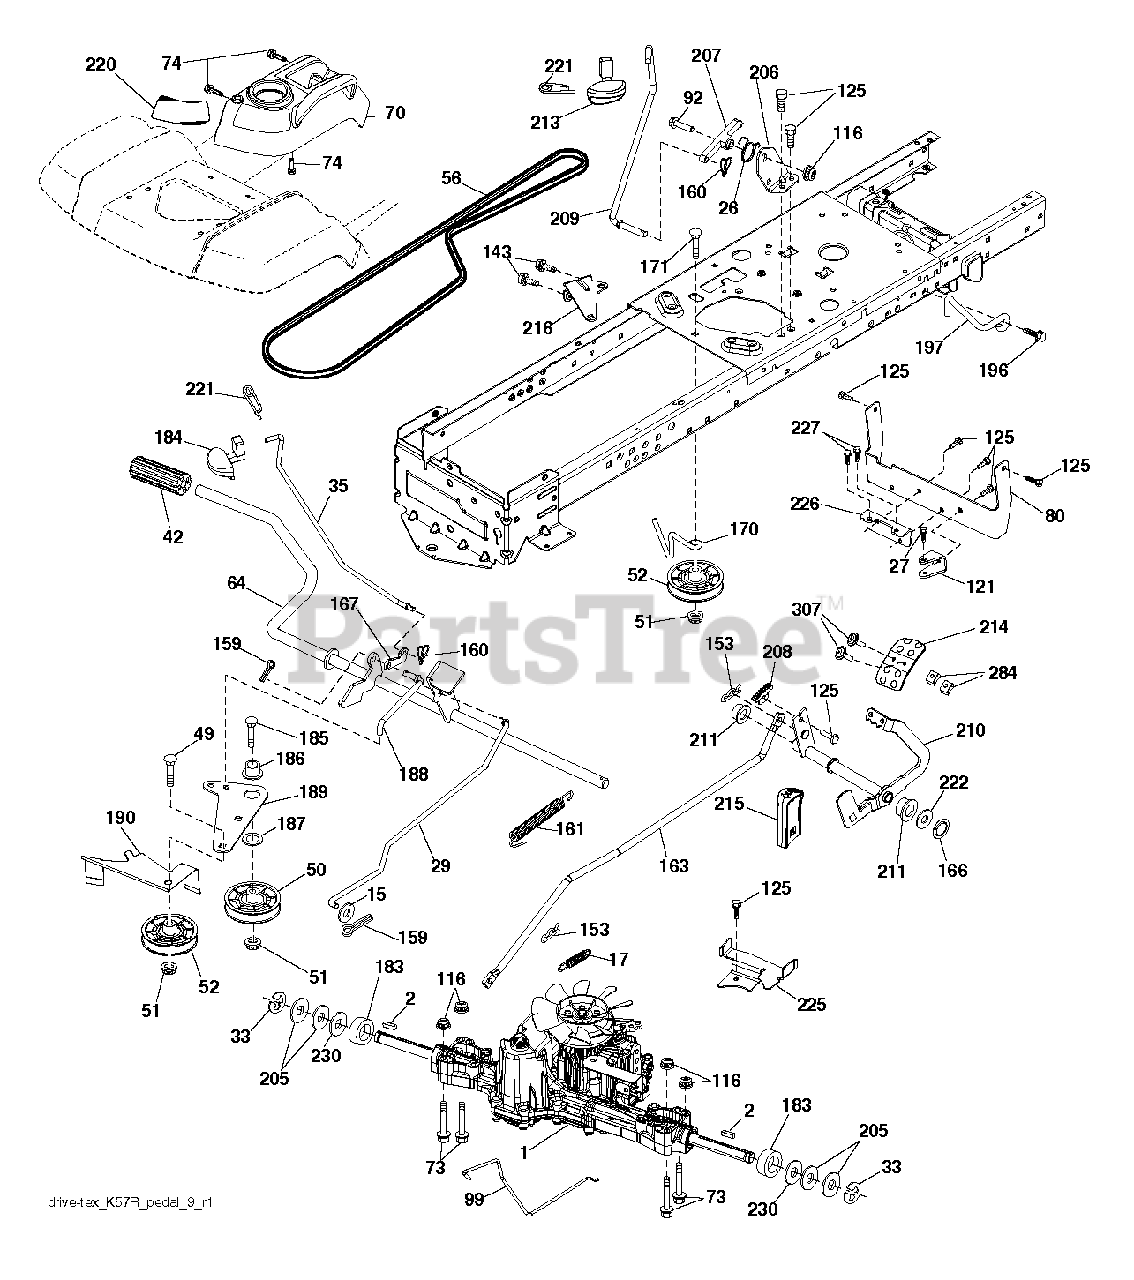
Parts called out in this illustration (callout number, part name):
2	SQUARE KEY
15	WASHER
17	SPRING.BRAKE.K46.GREEN
26	SPRING.RETURN.CRUISE
29	ROD.BRAKE.K46
33	E RING HYT
35	ROD .BRAKE. PARKING. GT. HUSQ.
42	PEDAL COVER T
50	IDLER.FLAT.910.OFFSET
51	NUT LOCK FLG 3/8-16 UNC
52	IDLER.V-GROOVE.910.OFFSET
56	V-BELT.MOWER.92.40.42/K46
64	SHAFT.ASM.PEDAL.BRK.CNTR
70	CONSOLE.ASM.RH.GT.FC.HUSQ
74	SCREW.HI-LO.CONSOLE
80	STRAP.TORQUE.K46.K57R.TT
92	BOLT
99	ROD.SPRING.BYPASS.K46.LT.Z
116	NUT LOCK HEX FLANGE 5/16-18
121	BRACKET.TORQUE.K57R.3POINT
125	SCREW
143	SCREW LT
153	RETAINER M
159	COTTER PIN
160	RETAINER CLIP
161	SPRING, RETURN LT
163	ROD.CONTROL.K57R.K46
166	NUT.PUSH.625
167	LATCH.BRAKE.SPRING
170	KEEPER.V-IDLER.CENTER.
183	SPACER AXLE
184	HANDLE.PARKING.BRAKE.H (BLK)
186	SPACER.RETAINER
187	WASHER 12/32X2X10GA
188	RP LINK.CLUTCH.GROUND.DRIVE
189	BELLCRANK.GROUND.DRIVE.TEX.
190	KEEPER.BELLCRANK.DRIVE
196	SCREW 3/8-16X1
197	LINK.CLUTCH.ANIT-ROTAT
206	BRACKET.MOUNT.CRUISE.LATCH
207	LATCH.CONTROL.CRUISE
208	GEAR.SECTOR.CONTROL.CR
209	ROD.CONTROL.CRUISE.GT.
210	ROCKER.ASM.PEDAL.CONTR
211	BEARING.NYLON
213	KNOB.CONTROL.CRUSIE.HU
214	PEDAL.FORWARD.HUSQVARNA.DEALER
215	PEDAL.COVER.REVERSE.CRD.X428BK
216	BRACKET.PULLEY.IDLER.W/TEX
220	REFLECTOR.RH.TEX GT
221	RETAINER.SPRING.CLIP.H
222	WASHER 21/32 X 1-1/4 X 10 GA.
225	KEEPER.BELT.TRANSAXLE.K46
226	BRACKET.MOUNT.TORQUE.K46.TLT
227	SCREW
230	WASHER.HARDENED
284	NUT.U-CHNL.1/4-20.550DP.350PNL
307	SCREW.MACHINE.CR.1/4-20
